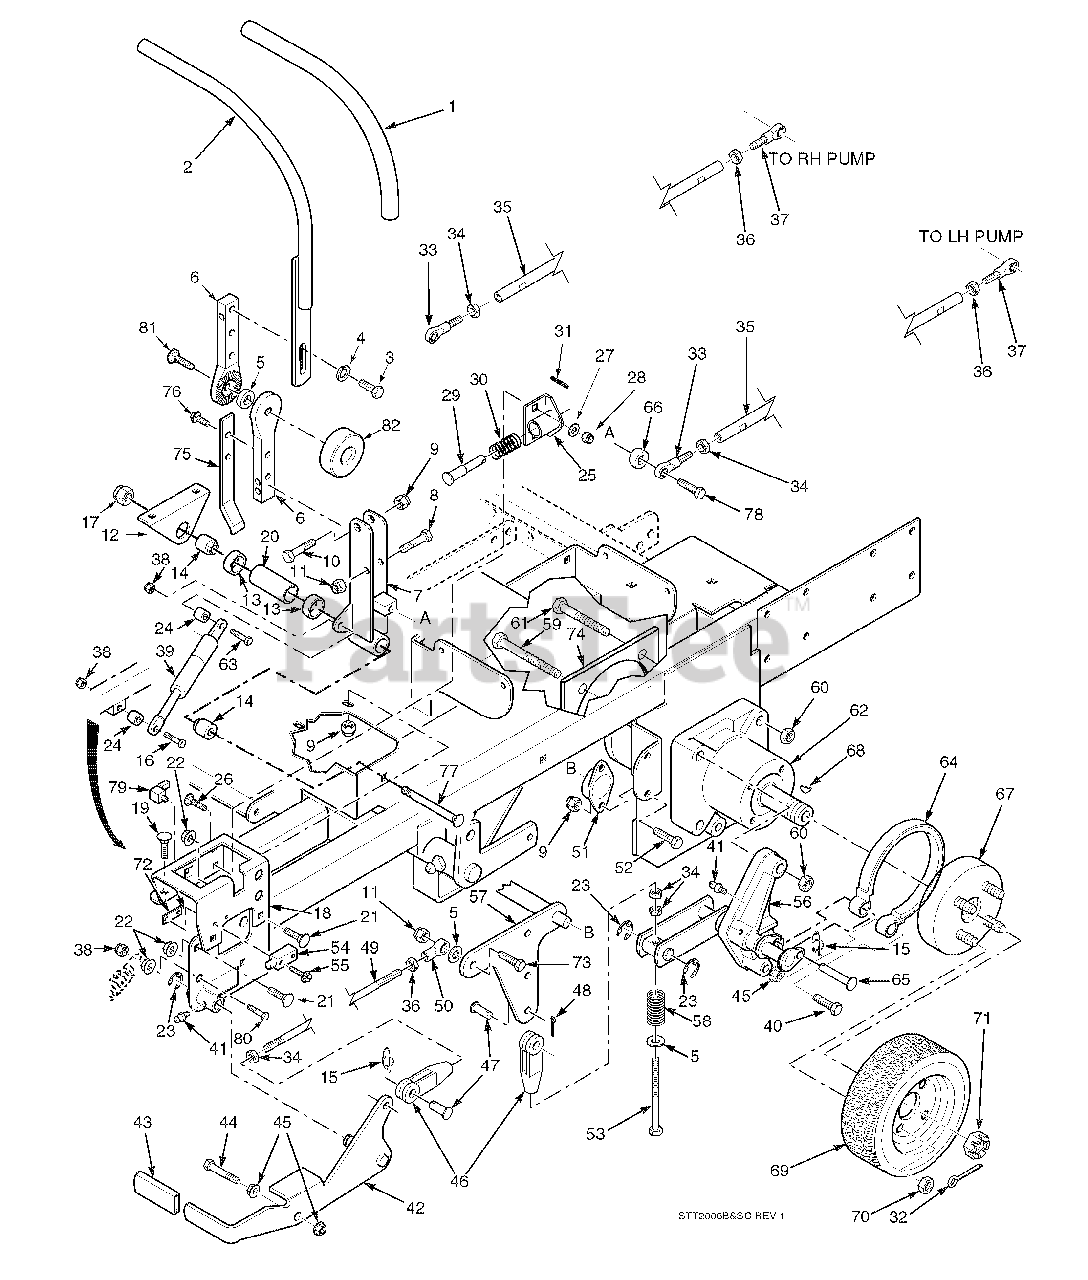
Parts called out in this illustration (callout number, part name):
1	Grip, Handle Bar
2	Handle Bar, LH
3	Bolt, Hex Head 5/16-18 x 1"
4	Lockwasher, 5/16"
5	Rubber Spacer
6	Bar, Control Lever
7	Control Lever Weldment, LH
8	Bolt, Hex Head 5/16-18 x 2"
9	Nut, Hex Elastic Stop 5/16-18
10	Bolt, Hex Head 3/8-16 x 2"
11	Nut, Hex Elastic Stop
12	Mount, Control Linkage
13	Ball Bearings, Neutral Return
14	Spacer
15	Pin, Rue Cotter 3/8 Dia.
16	Bolt, Hex Head, 5/16-18 x 2.75 Zinc
17	Nut, Hex Elastic Stop 5/8-11
18	Bracket, Control Lever LH
19	Bolt, Carriage 5/16-18 x 1"
20	Spacer, Bearing
21	Bolt, Carriage 5/16-18 x 3/4"
22	Nut, Hex Serrated Flange 5/16-18
23	Ring, Retaining 5/8" External "E"
24	Spacer
25	Bracket, Neutral Return
26	Bolt, Carriage 1/4-20 x 3/4"
27	Flatwasher, 1/4"
28	Nut, Hex Elastic Stop 1/4-20
29	Pin, Retaining Spring
30	Spring
31	Roll Pin, Spring 5/32 x 3/4"
32	Pin, Cotter 9/16 x 1-1/2"
33	Rod End, Male 3/8-24 RH Thread
34	Nut, 3/8-24 RH Thread
35	Tube, Control Link Air Cooled Engine
36	Nut, Hex 3/8-24 LH Thread
37	Rod End, Male 3/8-24 LH Thread
38	Locknut, 5/16-18, Elastic Stop
39	Gas Damper
40	Bolt, Hex Head 3/8-16 x 2-1/2”
41	Grease Fitting
42	Lever, Parking Brake
43	Grip, Parking Brake
44	Bolt, Hex Head 3/8-16 x 2-3/4"
45	Nut, Hex Serrated Flange 3/8-16
46	Clevis, Traction Control
47	Pin, Clevis 3/8-16 x 1-1/16"
48	Pin, Cotter 3/32 x .75
49	Rod, Parking Brake
50	Rod End, LH Thread
51	Bushing, Self Align
52	Bolt, Hex Head 5/16-18 x 3/4"
53	Bolt, Hex Hd 3/8-24 x 5-1/4", 23/4" Thrd
54	Switch
55	Screw, Hex SLTD WSHR Head #10 32 x 3/4"
56	Brake Linkage, LH
57	Bellcrank, Brake Actuator
58	Spring
59	Bolt, Hex Head 1/2-13 x 3-3/4"
60	Locknut, Hex 1/2-13 Center Lock
61	Bolt, Hex Head 1/2-13 x 2-1/2"
62	Wheel Motor, Ross
63	Bolt, Hex Head, 5/16-18 x 1.75, Zinc
64	Brake Band Assembly
65	Pin, Clevis 3/8" Dia. x 1.93"
66	Spacer
67	Wheel Hub/Brake Drum Assembly
68	Key, Woodruff 5/16 x 1”
69	Wheel Assembly 24 x 12-12 Turf Master
70	Lug Nut, 1/2-20
71	Nut, Hex Castle
72	Threaded Plate
73	Bolt, Hex Head 3/8-16 x 1-1/2"
74	Plate Weldment, Motor Backing
75	Actuator Switch
76	Bolt, Hex Serrated Flange 5/16-18 x 3/4"
77	Bolt, Carriage 3/8-16 x 4-3/4”
78	Bolt, Hex Head 3/8-16 x 1”
79	Switch
80	Bolt, Hex Head 3/8-16 x 1-1/4” Grade 8
81	Bolt, Carriage 5/16-18 x 1-1/2”
